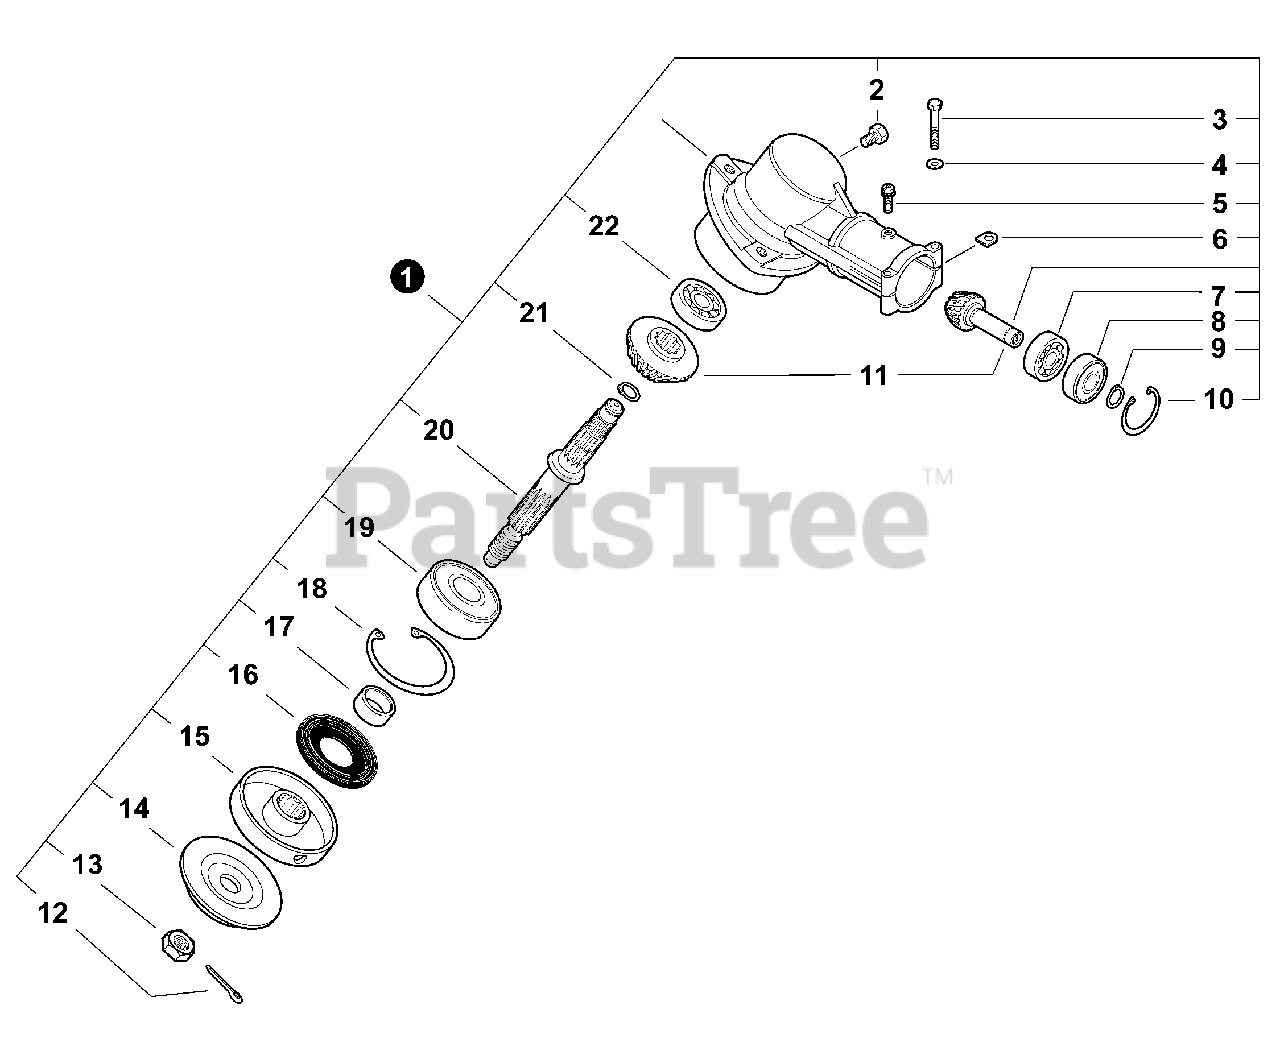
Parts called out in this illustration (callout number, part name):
1	GEAR CASE ASY
2	BOLT - 8×8
3	BOLT - 5×35
5	SCREW - 5×10
6	WASHER, SHIM
7	BEARING, BALL - 6900
8	BEARING, BALL - 6900Z
9	RING, RETAINING - 10
10	RING, RETAINING - 22
11	GEAR SET - BEVEL
12	PIN, SPLIT - 2X22
13	NUT - 10 -- LEFT HAND
14	PLATE, ADAPTER - LOWER
15	ADAPTER, BLADE - UPPER
16	SEAL, OIL
18	RING, RETAINING - 32
19	BEARING, BALL - 6201
20	GEAR, SHAFT
21	RING, RETAINING - 12
22	BEARING, BALL - 609
